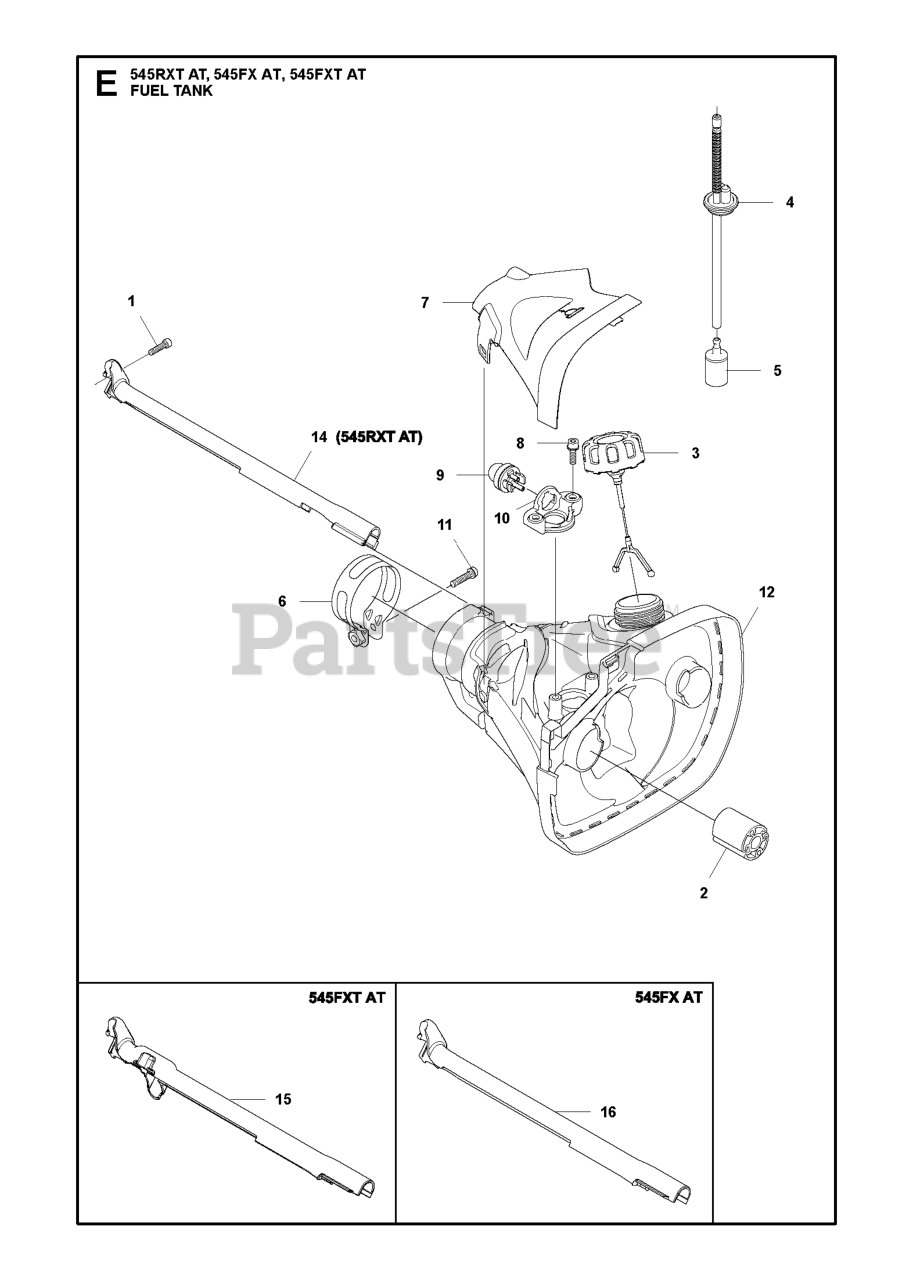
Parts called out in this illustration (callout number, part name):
1	CABLE POSITIVE, LONG
2	ANTIVIBRATION ELEMENT
2	CABLE-NEGATIVE
4	SWITCH, BRAKE 3P
5	RP FUEL FILTER
5	FUSE, 7.5 AMP 32 VOLT ATO
6	CLAMP ASSY
6	FUSE, 20 AMP 32 VOLT ATO
7	COVER LID FUEL TANK HVA
7	RP IGNITION SWITCH
8	RP SWITCH.PTO.TERMINAL.STD.RED
9	AIR PURGE BUBBLE
9	HOUR METER
10	FRAME HARNESS
11	SCREW IHSCFM
11	HCS 5/16C X 3/4
12	FUEL TANK ASSY HVA
12	NUT 5/16 NYLOC
13	NUT 10-24 NYLOC
14	PROTECTOR
14	SCREW, #1--24 X 1/2 SLOTTED
15	PROTECTOR
15	KAW PIGTAIL
16	PROTECTOR
16	NUT 1/4C CENTERLOCK
17	WASHER 1/4 INT TOOTH
19	HCS 1/4C X 5/8
21	BATTERY, 12 V 330 AMP
22	POST.CABLE LONG
24	KEY
25	PUSH-MOUNT WIRE CLIP
